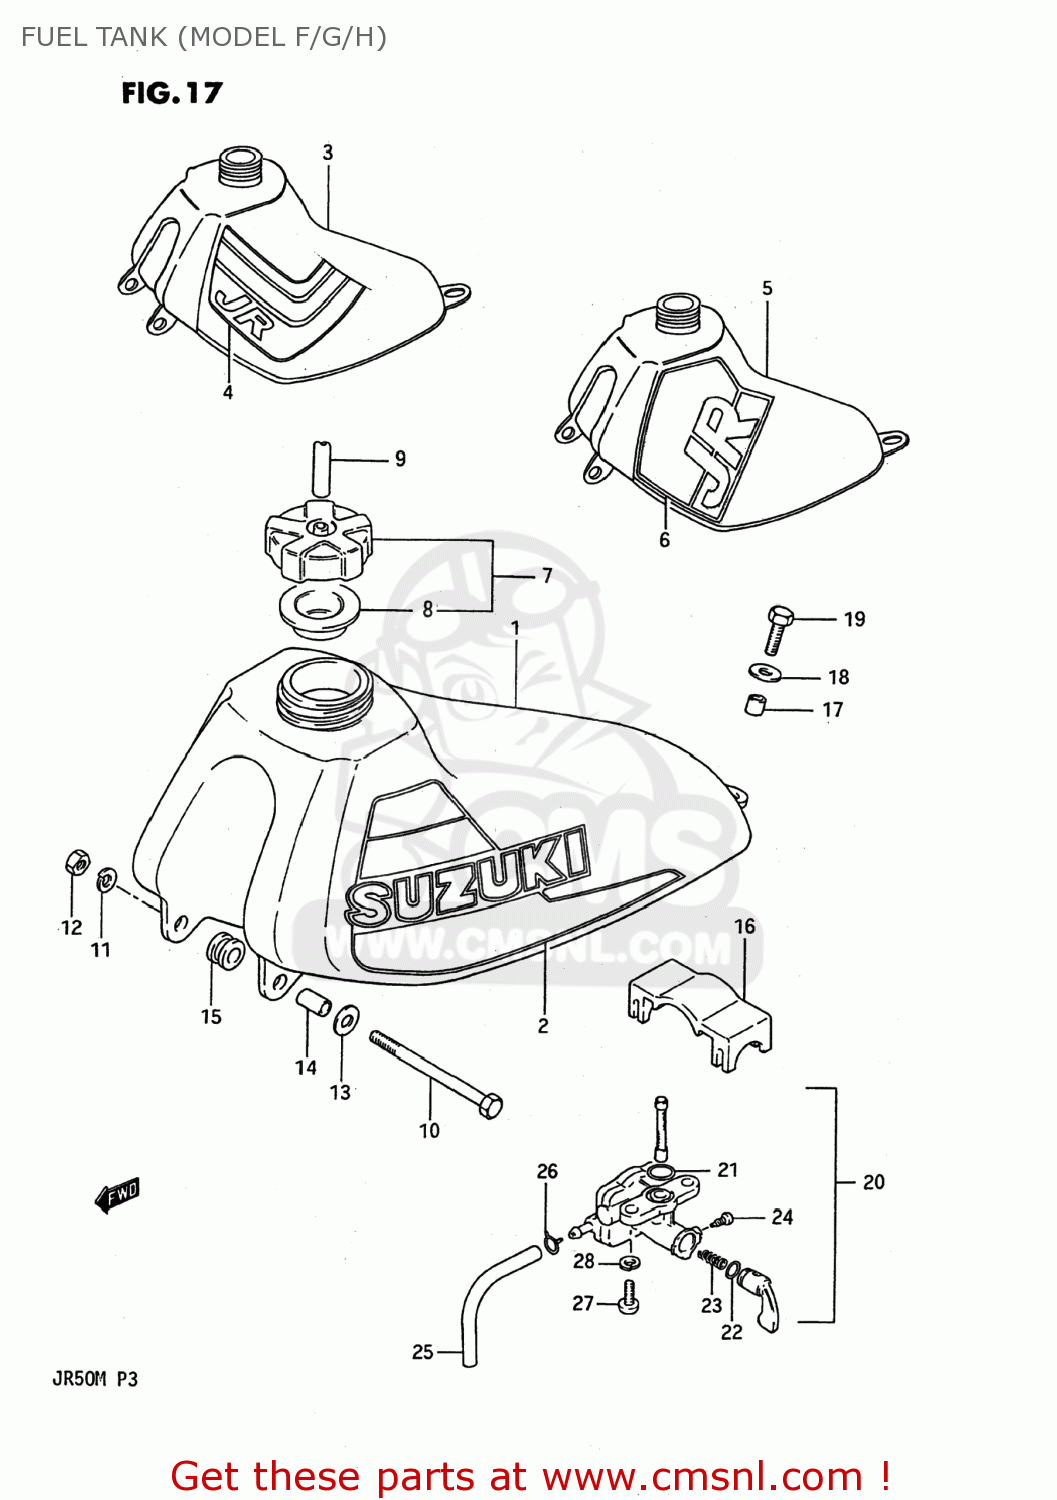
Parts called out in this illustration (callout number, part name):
1	TANK ASSEMBLY,FUEL
2	TAPE SET,FUEL TANK
3	TANK ASSEMBLY,FUEL
4	TAPE SET,FUEL TANK
5	TANK ASSEMBLY,FUEL
6	TAPE SET,FUEL TANK
7	CAP,FUEL TANK FILLER
8	GASKET,FUEL TANK CAP (NAS)
9	HOSE
10	BOLT
11	WASHER,LOCK
12	NUT 6MM
13	WASHER(6.5X18X1)
14	SPACER (6.8X10X11.5)
15	CUSHION
16	CUSHION,FUEL TANK UPR
17	SPACER
18	WASHER(6.5X18X1)
19	BOLT
20	COCK ASSY,FUEL
21	O RING
22	O RING,LEVER
23	SPRING,FUEL COCK VALUE
24	SCREW
25	HOSE
26	CLIP
27	SCREW
28	WASHER,LOCK
